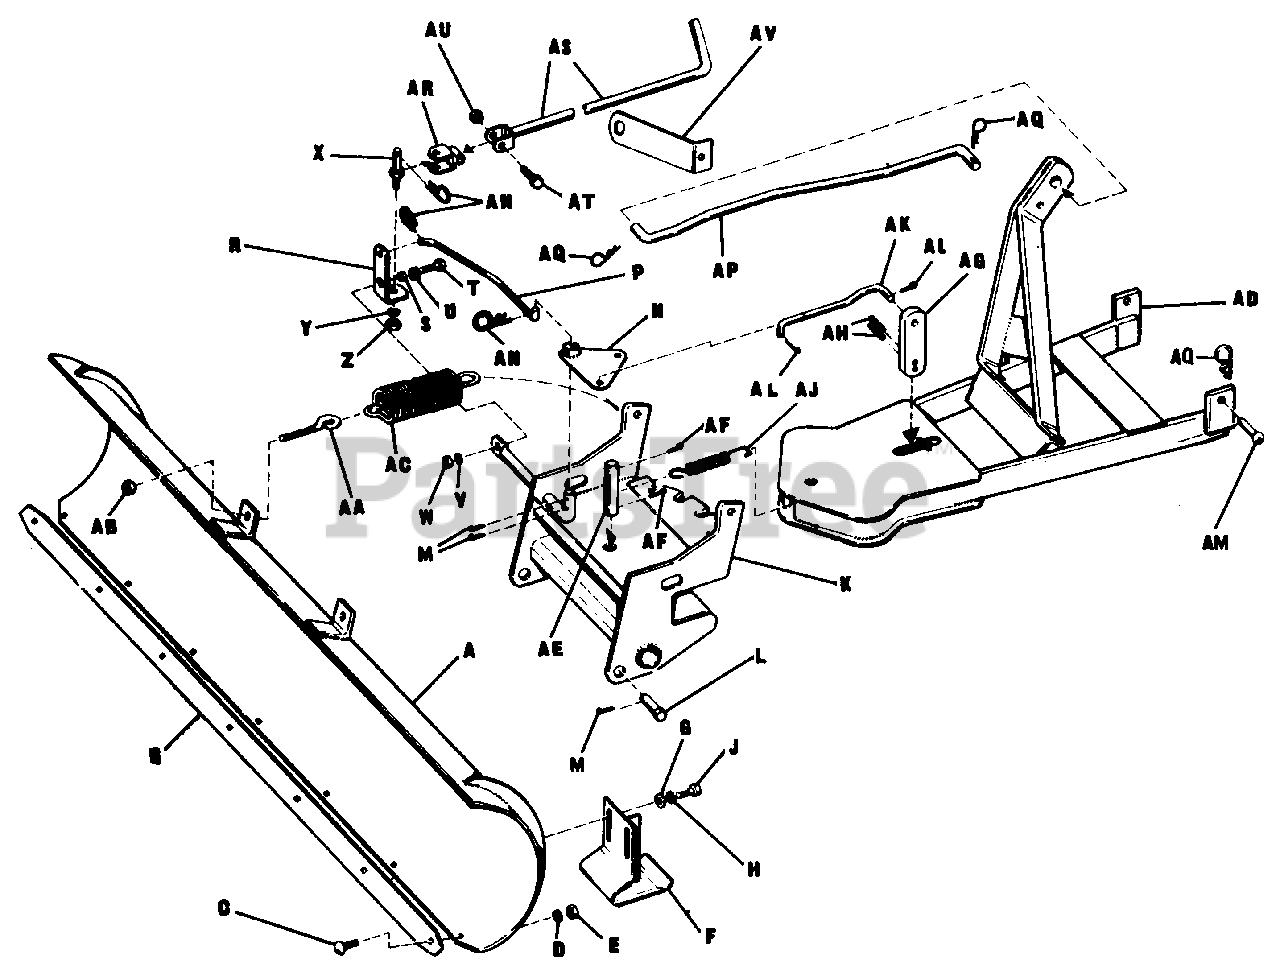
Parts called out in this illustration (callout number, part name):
A	Blade Ass'y
C	Carriage Bolt, 3/8"-16 x 1" lg.
D	Lock Washer 3/8"
E	Full Hex Nut 3/8"-16 N.C.
F	Shoe Ass'y.
G	Flat Washer 3/8"
H	Lock Washer 3/8"
J	Hex. Cap Screw 3/8"-16 x 3/4'
K	Pivot Frame Ass'y
M	Cotter Pin 1/8 Dia. x 1"
N	Pivot Plate Ass'y
R	Pivot Arm
T	Hex Cap Screw 5/16"-18 x 1" lg.
U	Plain Washer 5/16"
V	Lock Washer 5/16".
W	Full Hex. Nut 5/16"-18 N.C.
Y	Lock Washer 5/16"
Z	Full Hex. Nut 5/16"-18
AB	Full Hex. Nut 5/16"-18
AD	Push Bar Ass'y
AE	Pivot Pin 5/8" Dia. x 3-3/8" lg.
AF	Cotter Pin 3/16 x 1-1/4" lg.
AH	Roll Pin 7/32" Dia. x 1" lg.
AJ	Latch Spring
AL	Cotter Pin 3/32" Dia. x 5/8"
AM	(Hitch) Pin
AN	Spring Clip
AP	Front Lift-Rod
AQ	Spring Clip
AS	Handle Ass'y
AT	Hex. Cap Screw 5/16'-18 x 1-1/2"
AU	Full Lock Hex. Nut 5/16"-18
